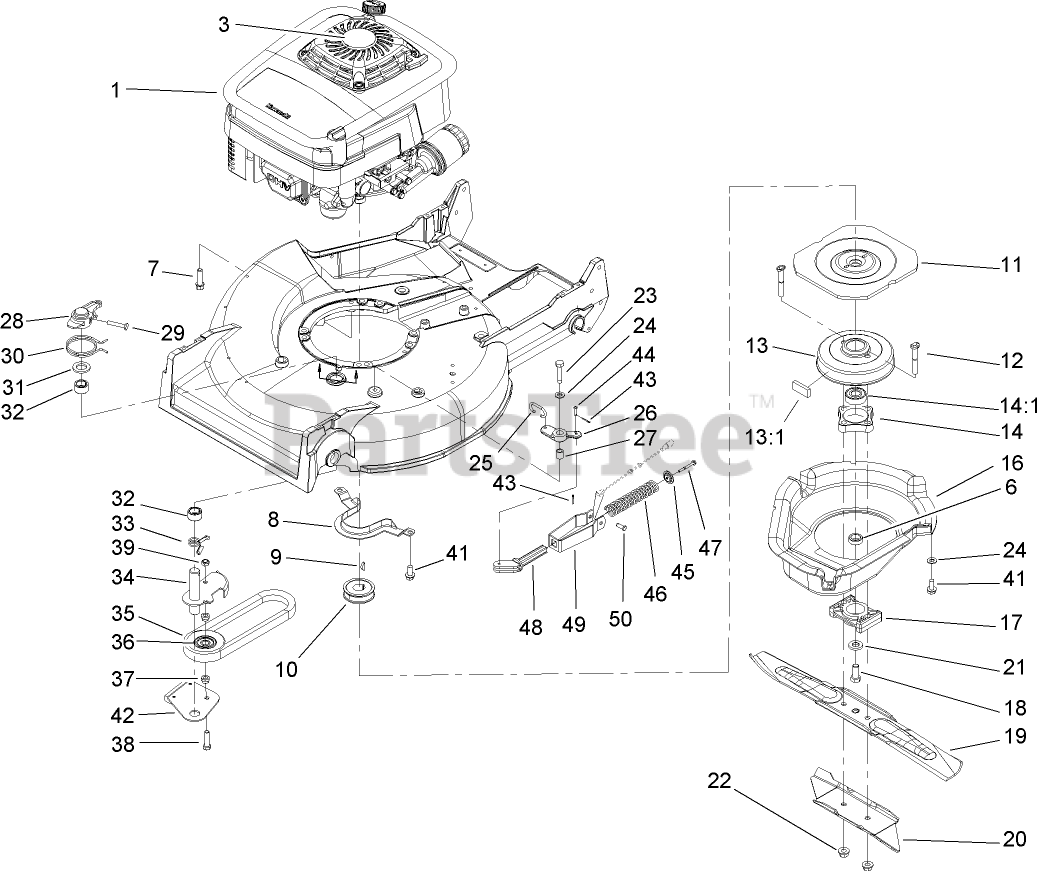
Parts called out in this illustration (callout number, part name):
1	Engine ASM
6	SPACER-SHAFT, OUTPUT
7	SCREW-TAPTITE
8	BRACKET-GUIDE, BELT
9	KEY-WOODRUFF
10	PULLEY-DRIVER
11	FLYWHEEL - BBC
12	BOLT-BLADE
13	BRAKE DRUM ASM
13:1	DAMPENER-VIBRATION
14	HUB ASM
16	SHIELD
17	SPACER-BLADE
18	SCREW-HH
19	BLADE-21 INCH
20	STIFFENER-BLADE
22	NUT-LOCK
23	SCREW-HH
24	WASHER-PLAIN
25	LINK-CONTROL
26	BELLCRANK
27	SLEEVE-BELLCRANK
28	LEVER
29	SCREW-HH
30	SPRING-TORSION
31	WASHER
32	BEARING
33	SPRING-TORSION
34	ARM-IDLER
35	V-BELT
37	SPACER-PULLEY, IDLER
38	SCREW-HH
39	NUT-LOCK, NI
41	SCREW-HWHTF
43	PIN-COTTER
44	PIN-SPRING
45	RETAINER-SPRING
46	SPRING
47	SCREW-HWHTF
48	GUIDE-SPRING
49	BRACKET-SPRING
50	PIN-CABLE
